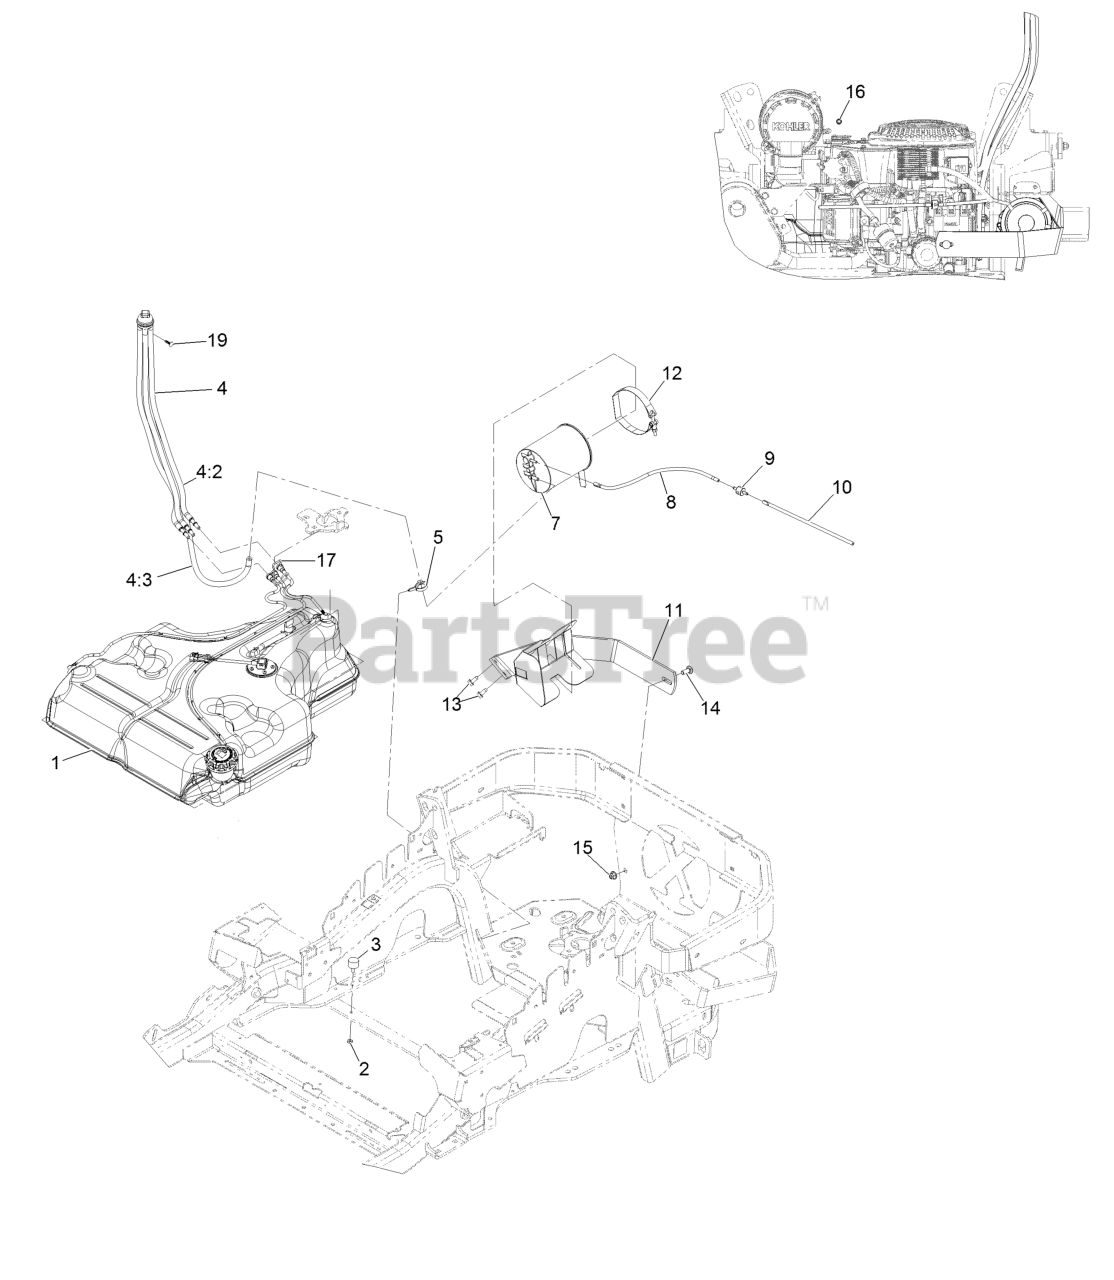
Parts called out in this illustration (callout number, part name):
1	Fuel Tank ASM
2	Nut-Jam 1/4-20
4	Fuel Manifold Vent ASM
4:2	Hose-Fuel Line 24"
4:3	Hose-Fuel
5	Clamp-Hose
7	Canister-Carbon, 1200Cc
8	Hose-Vent, Formed
9	Valve-Check, Vacuum
10	Hose-Vent, Formed
11	Mount-Canister
12	Clamp, T-Bolt
13	Screw-HWH 5/16-18 X 3/4 Tf
14	Bolt-Carriage 3/8-16 X 1
15	Nut-Nyloc 3/8-16 Flg
16	Plug-Port
17	Retainer-Line, Vapor
19	Plug-Plastic
